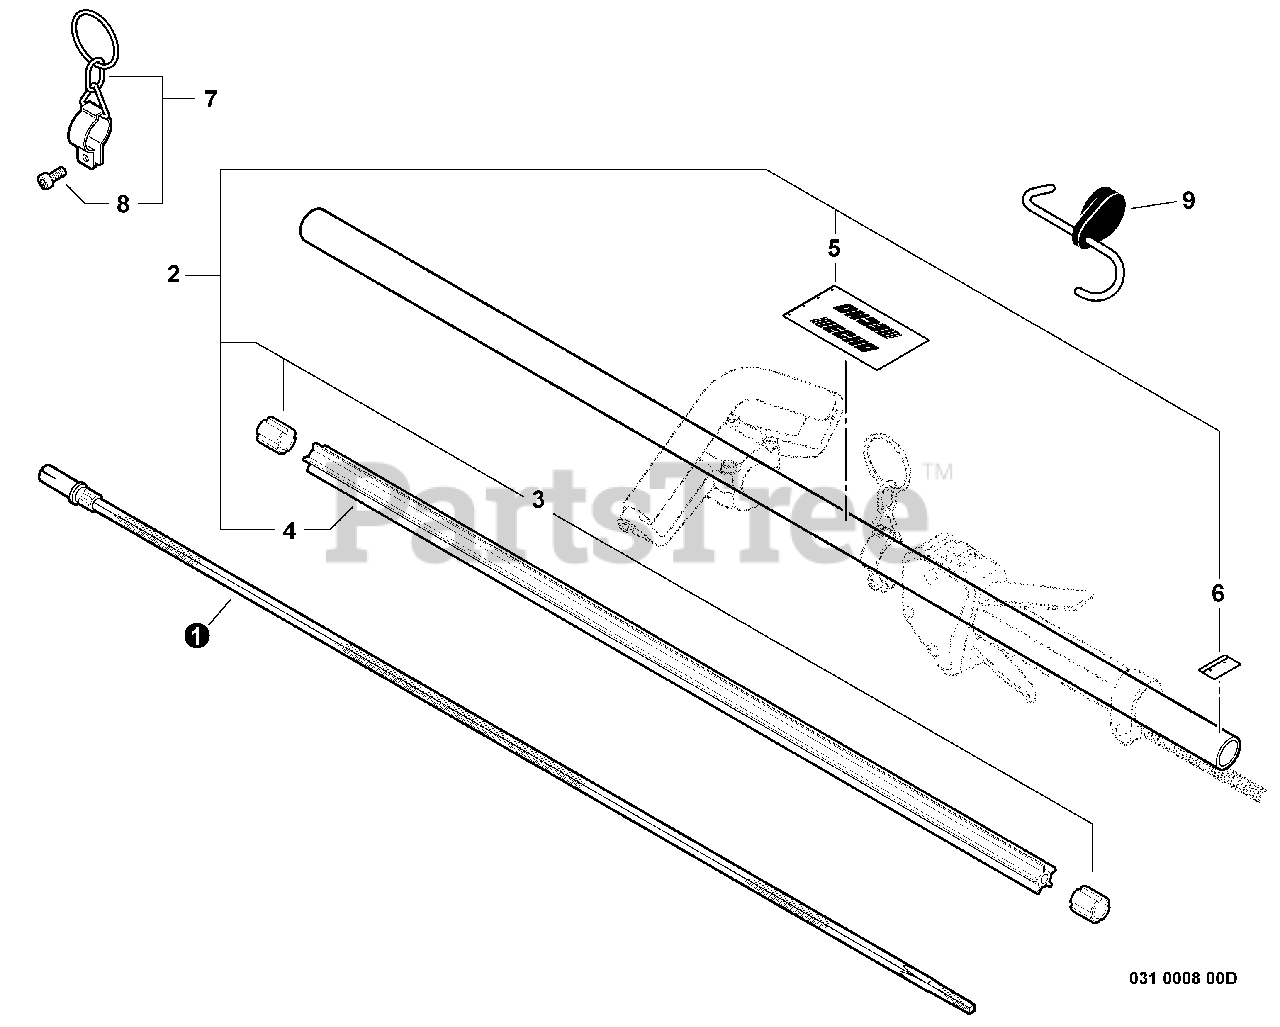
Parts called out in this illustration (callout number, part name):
1	DRIVESHAFT - FLEXIBLE
2	MAIN PIPE ASSY
4	LINER - FLEXIBLE
5	LABEL - HANDLE LOCATION
6	LABEL - ALIGNMENT
7	HANGER KIT
8	SCREW - 5X12
9	PAS ATTACHMENT HANGER
